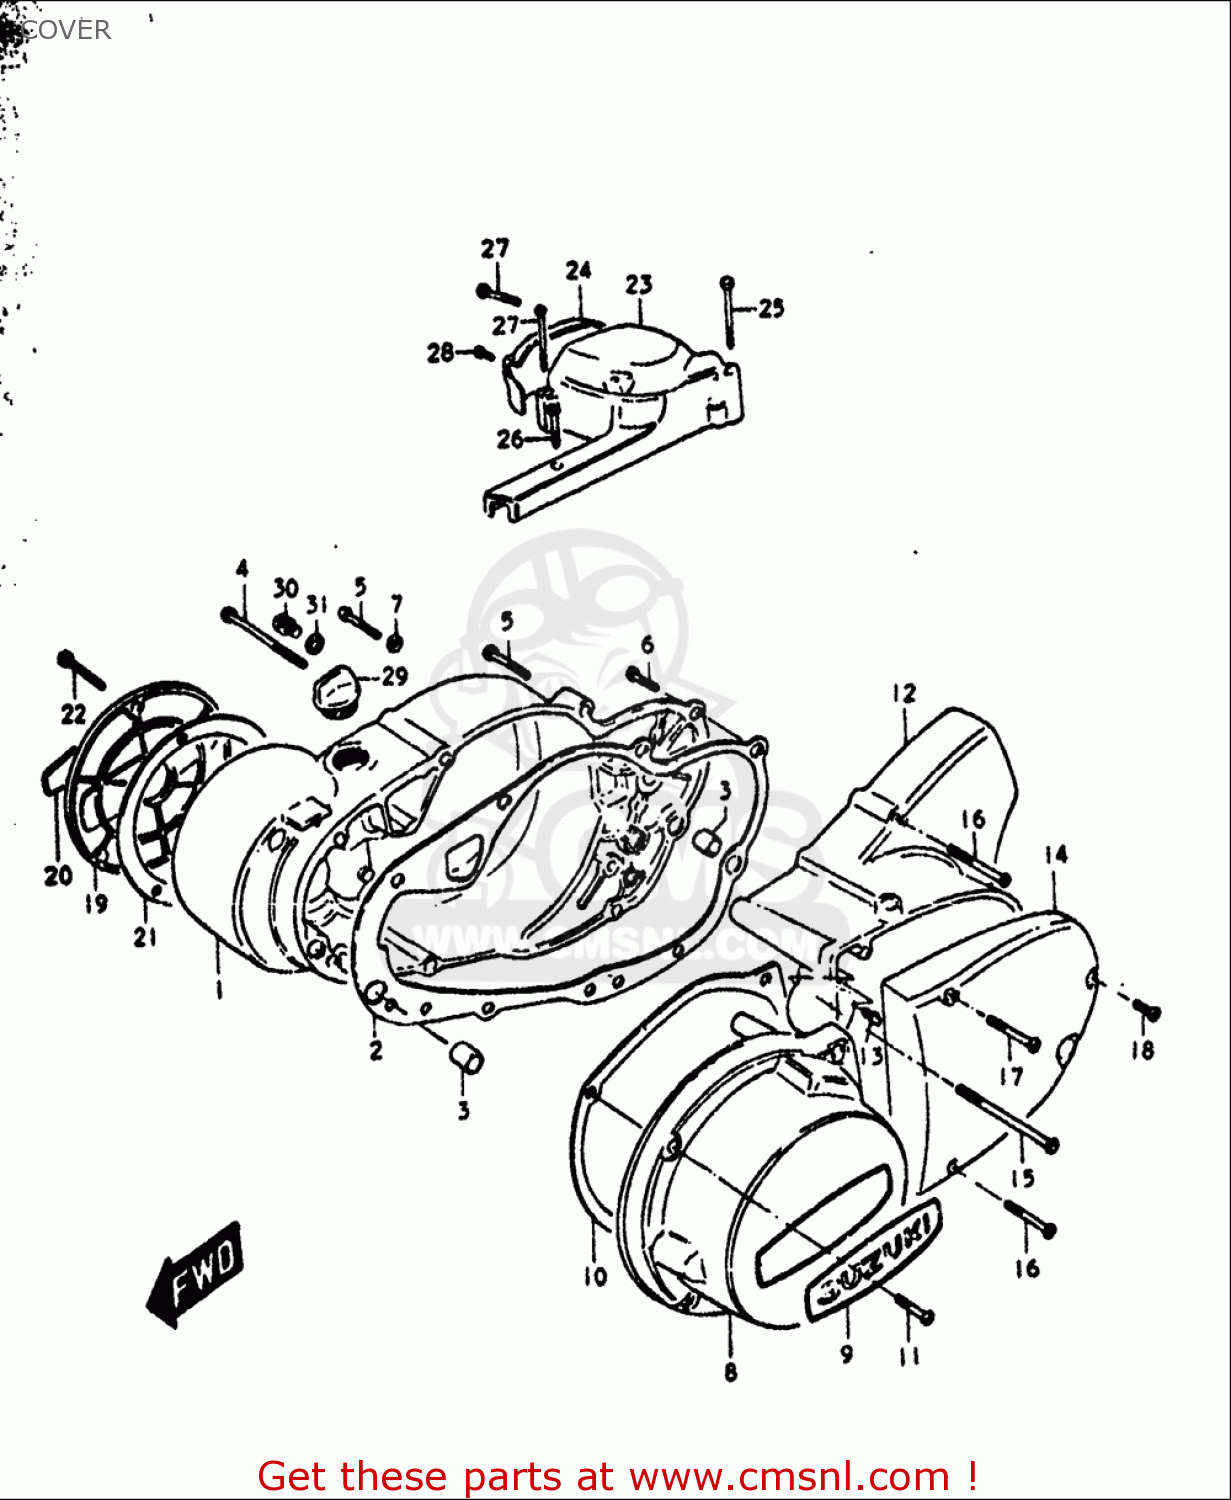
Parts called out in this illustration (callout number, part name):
2	GASKET,CLUTCH COVER (NAS)
3	PIN(10.4X13X22)
4	SCREW
5	SCREW
6	SCREW
7	WASHER(6.5X18X2)
9	EMBLEM,GENERATOR COVER
10	GASKET,MAGNETO COVER (MCA)
11	SCREW
13	NIPPLE
15	SCREW
16	SCREW
17	SCREW
18	SCREW
20	EMBLEM,CONTACT BREAKER CAP
21	GASKET,CONTACT BREAKER CAP (NAS)
22	SCREW
25	BOLT 5X45
26	BOLT
27	SCREW
28	SCREW
29	PLUG SET
30	SCREW(6X10)
31	GASKET(6.2X11X1) (NAS)
